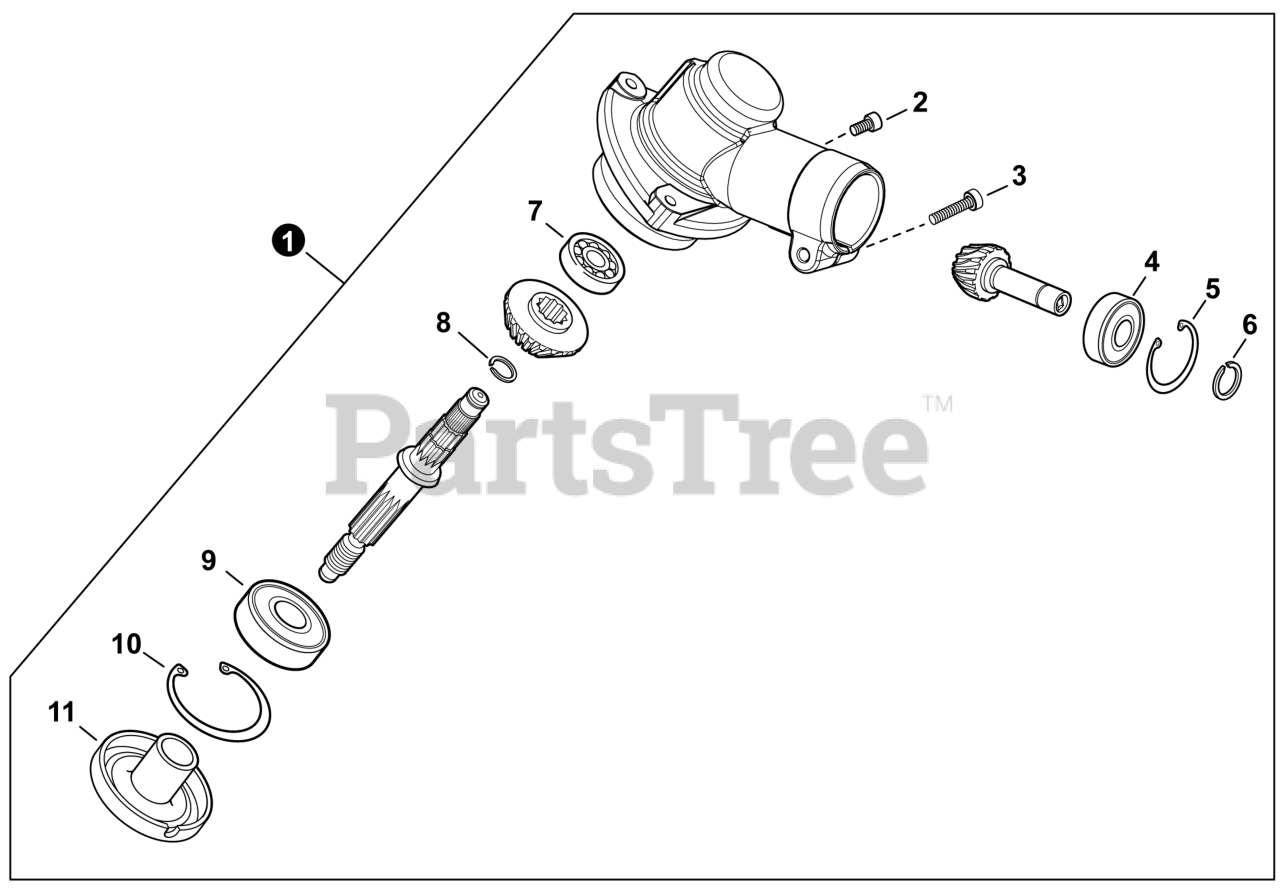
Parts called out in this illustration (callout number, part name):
1	GEAR CASE ASSY
2	BOLT, TORX 5x12
3	BOLT, TORX 5x25
4	BEARING, BALL 609ZA
5	RING, SNAP 24
6	RING, SNAP 9
7	BEARING, BALL 609A
8	RING, SNAP 12
9	BEARING, BALL 6201 2RS
10	RING, SNAP 32
11	PLATE, ADAPTOR - UPPER
